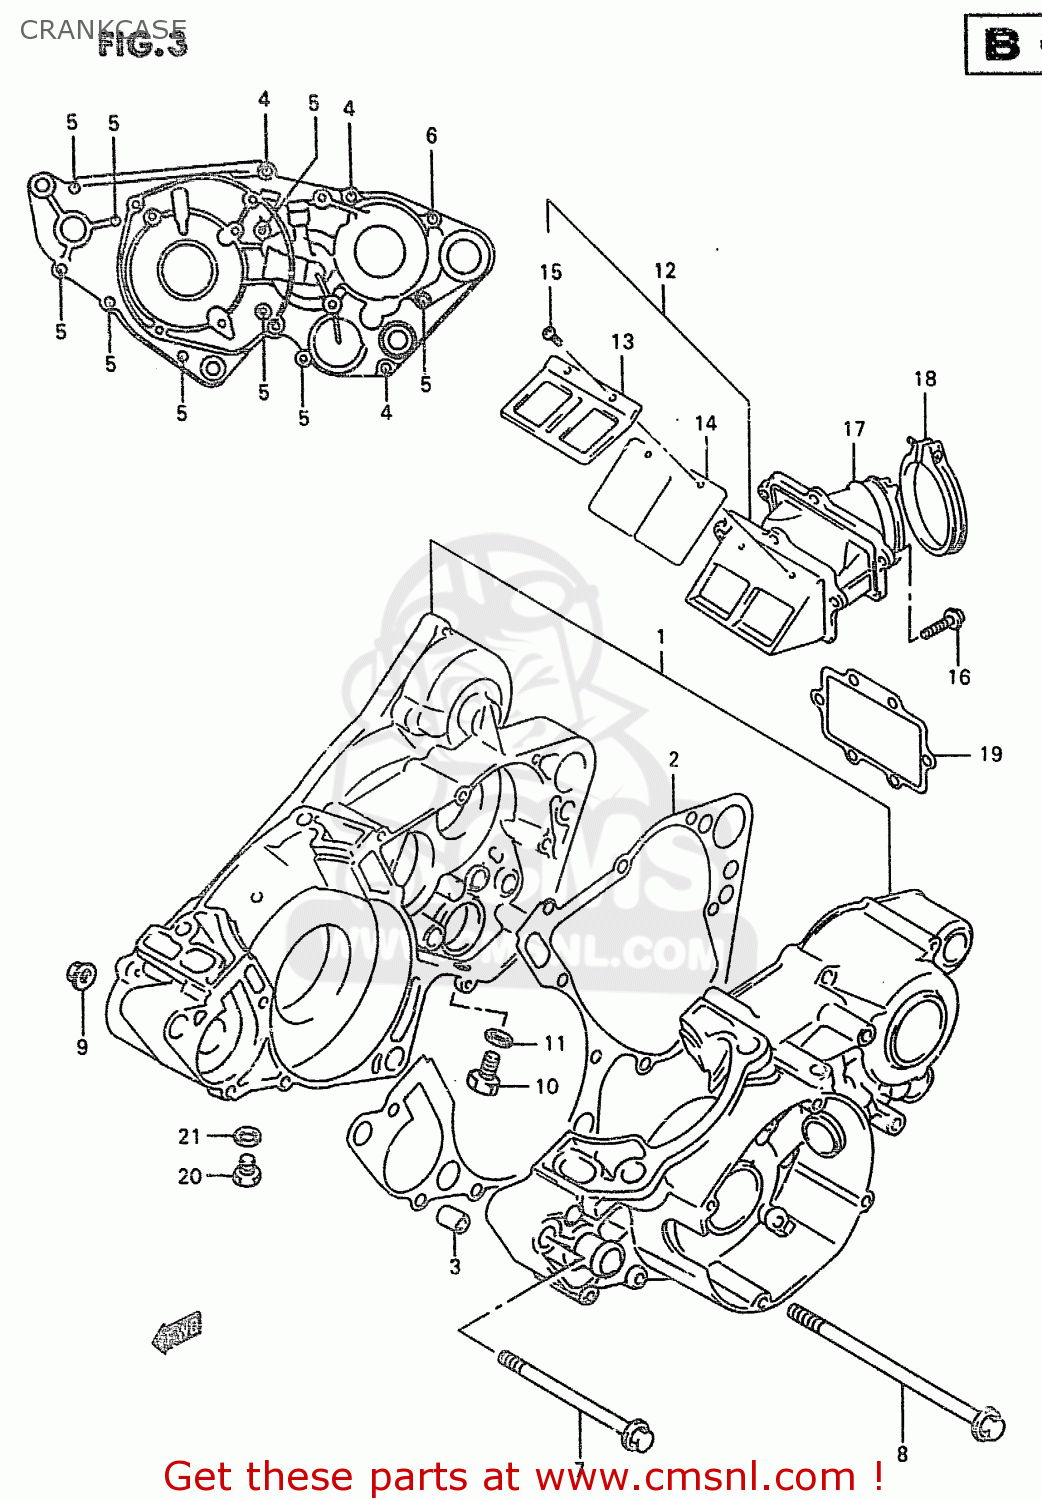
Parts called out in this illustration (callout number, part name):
1	CRANKCASE SET
2	GASKET,CRANKCASE
3	PIN(13X10.4X20)
4	BOLT
5	BOLT
6	BOLT
7	BOLT(10X105)
8	BOLT(10X140)
9	NUT
10	Bolt
11	GASKET(12.1X16.2X3.7) (NAS)
12	VALVE ASSY,REED
13	STOPPER,REED VALVE
14	VALVE,REED
15	SCREW
16	SCREW
17	PIPE,INTAKE
18	CLAMP
19	GASKET,REED VALVE
20	BOLT,DRAIN
21	GASKET 8.2X14X1 (NAS)
